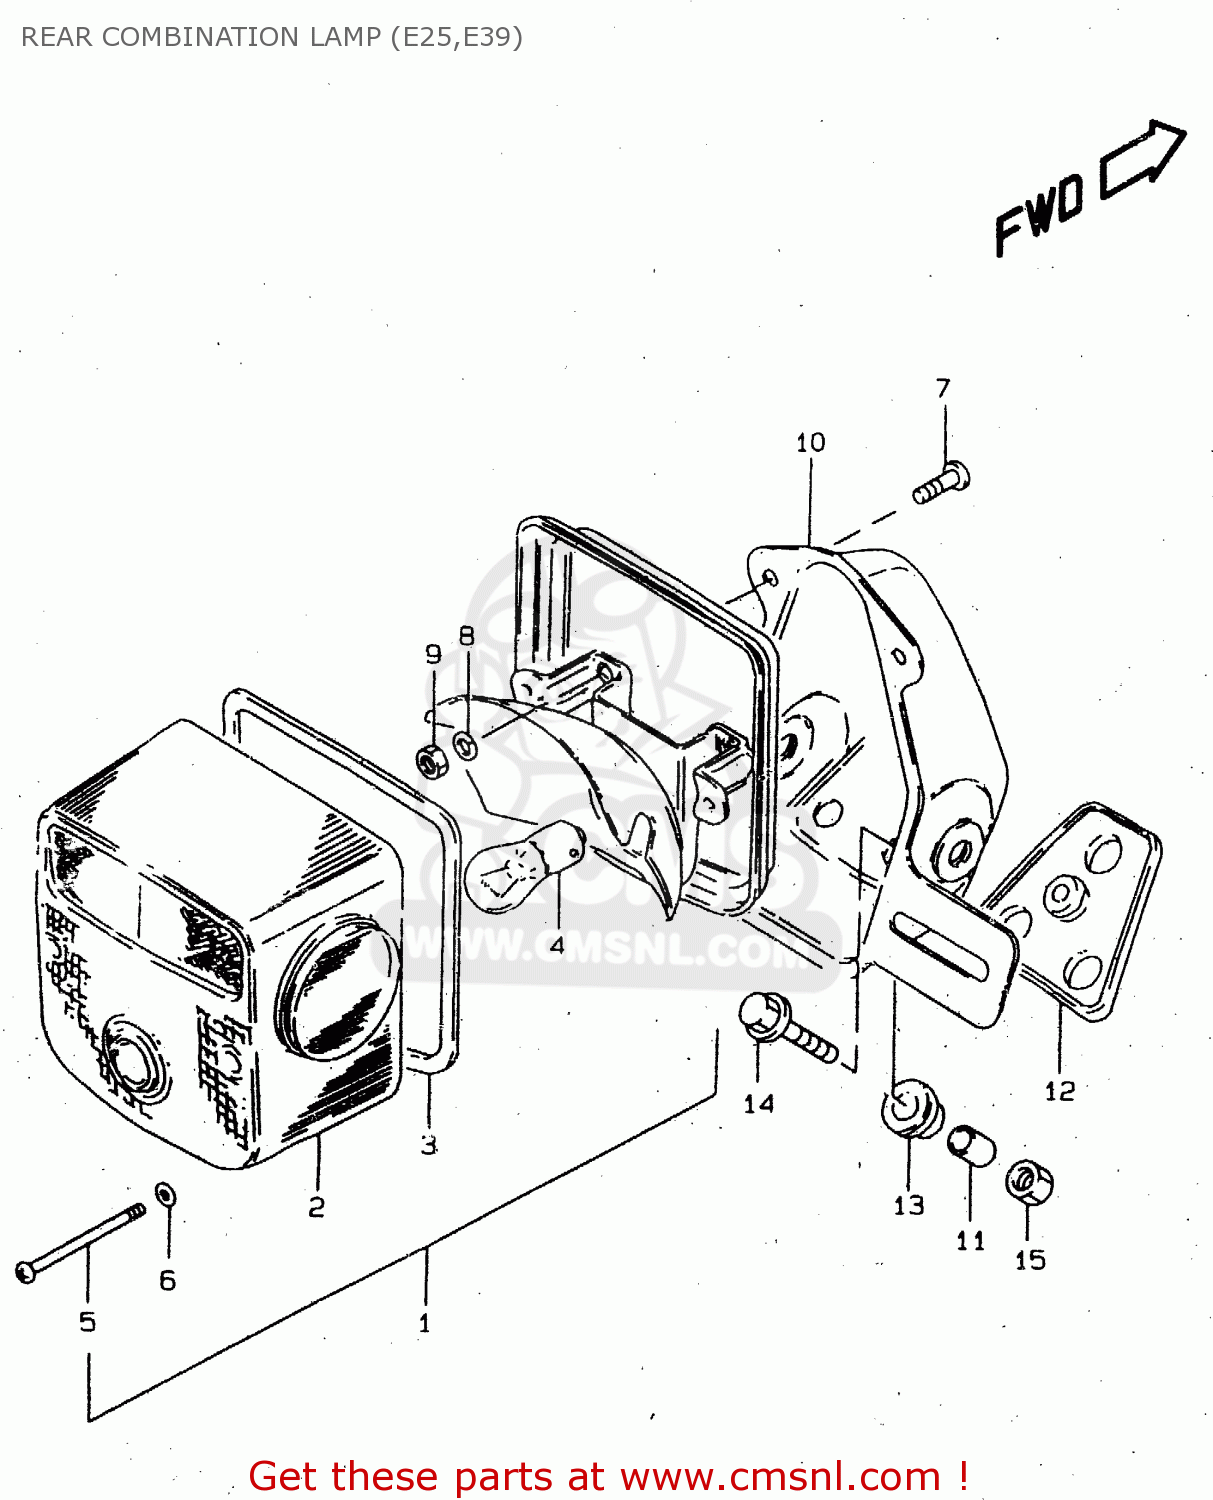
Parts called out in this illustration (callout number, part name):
1	LAMP UNIT,RR COMBNATION
2	LENS
3	GASKET (NAS)
4	BULB 12V21/5W
5	SCREW (4X55)
6	GASKET (NAS)
7	SCREW
8	WASHER,LOCK
9	NUT
10	BRACKET UNIT,TAIL LAMP
11	SPACER
12	CUSHION
13	CUSHION
14	BOLT(6X20)
15	NUT 6MM
